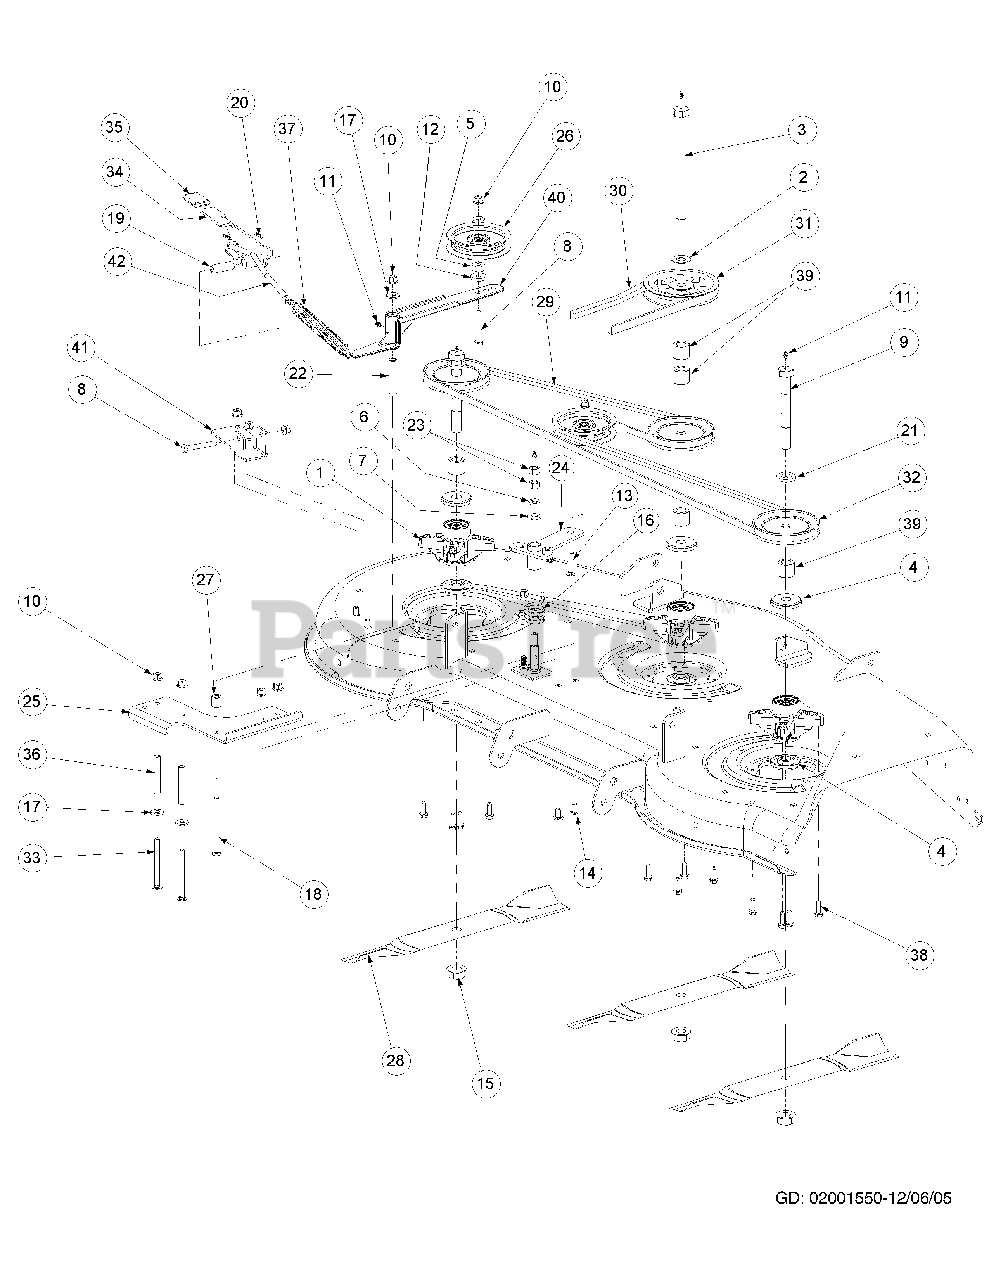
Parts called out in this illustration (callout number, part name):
1	Spindle Assembly
2	Washer, .76 x 1.49 x .06
3	Hex Cap Screw, 3/4-16 x 8.50
4	Spindle Spacer
5	Spacer .406 ID x 1.0 OD
6	Lock Washer, 1/2
7	Washer, 1/2 Zinc
8	Hex Cap Screw, 3/8-16 x 2.50
9	Hex Cap Screw, 3/4-16 x 6.00
10	Hex Nut, 3/8-16, Flange Lock
11	Grease Fitting, 1/4-28 x 3/16
12	Washer, .4375 ID x 1.75 OD x .25
13	Hex Carriage Screw, 3/8-16, 1.50
14	Carriage Bolt, 3/8-16 x .75
15	Hex Flange Nut, 3/4-16
16	Torsion Idler Spring
17	Flat Washer, .406 ID, 1.0 OD, .105
18	Hex Cap Screw, 3/8-16 x 4-1/2
19	Spacer, .39 x .63 x 1.75
20	Cotter Pin, .072 x 1.12 Lg
21	Spacer .812 ID x .218
22	Spacer, .39 ID x .625 OD x 2.75
23	Hex Nut, 1/2-20
24	Idler Arm Assembly
24	Bearing
25	Idler Arm Mounting Bracket
26	Idler Pulley, 4.06 OD
27	Spacer, .39 ID x .875 OD x 1.00
29	V Belt, A Section x 120.0
30	V Belt, B Section x 84.2
31	V-Pulley, 5.774 OD
32	Pulley, A Sect x 4.90
33	Carriage Bolt, 3/8-16 x 4.00
34	Handle Tension Weldment
35	Handle Tension Grip
36	Spacer, .385 x .50 x 3.045
37	Extension Spring, 1.0 x OD x 5.00
38	Self Tapping Screw 5/16-18 x 1.00
39	Spacer, .78 x 1.25 x 1.0425
40	Idler Arm Assembly, Top
41	Idler Tension Mounting Bracket
42	Spring Tension Rod
